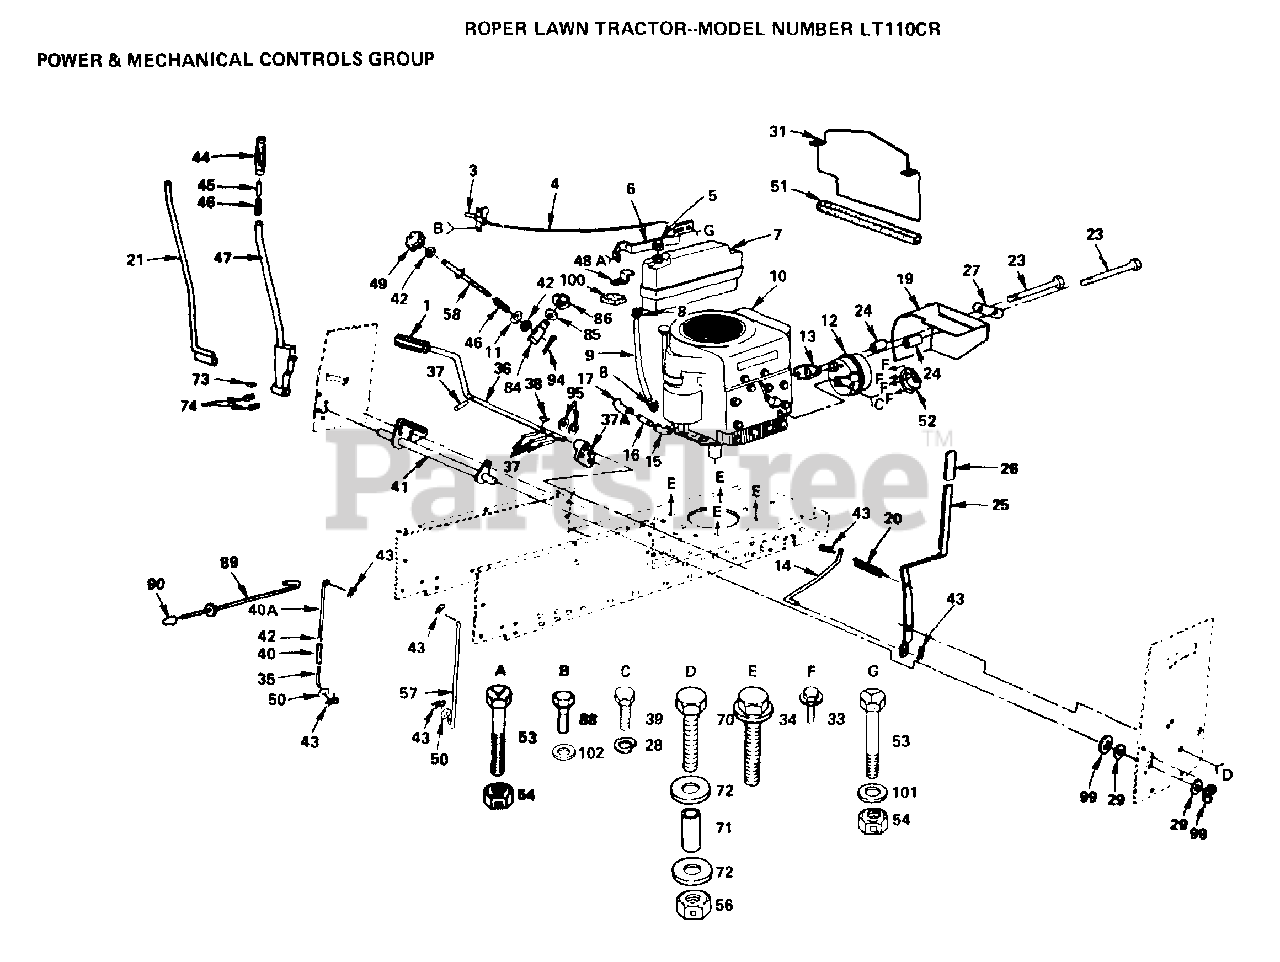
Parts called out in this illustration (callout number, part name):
1	PEDAL COVER T
6	SUPPORT-TANK LT
9	HOSE T
11	WASHER
12	MUFFLER LTV
15	STREET ELBOW LT
16	PIPE NIPPLE
17	ELBOW
19	BAFFLE ASSY LT
20	"SPRING.EXT.8.5"""
21	ROD ASSY-LEVER LT
23	BOLT YT
24	SPACER LT
25	HANDLE-CLUTCH L
27	CLIP-MUFFLER LT
28	LOCKWASHER
29	WASHER
31	"VERTICAL LT, BAFL"
34	SCREW
35	LINK LIFT LT
36	SHAFT PEDAL LT
39	BOLT
40A	LINK LIFT LT
41	SHAFT ASSY - LIFT
42	NUT
44	HANDLE GRIP T
46	SPRING T
47	LEVER ASSY LT
48	BRACE-TANK LT
50	WASHER
52	DEFLECTOR.222573
53	BOLT
58	ROD ADJUST LT
71	BUSHING LT
72	WASHER GT
85	WASHER
86	KLIP RING
88	SCREW LT
90	PLUNGER CAP T
99	RING
100	PAD-SPACER T
101	WASHER
102	WASHER
